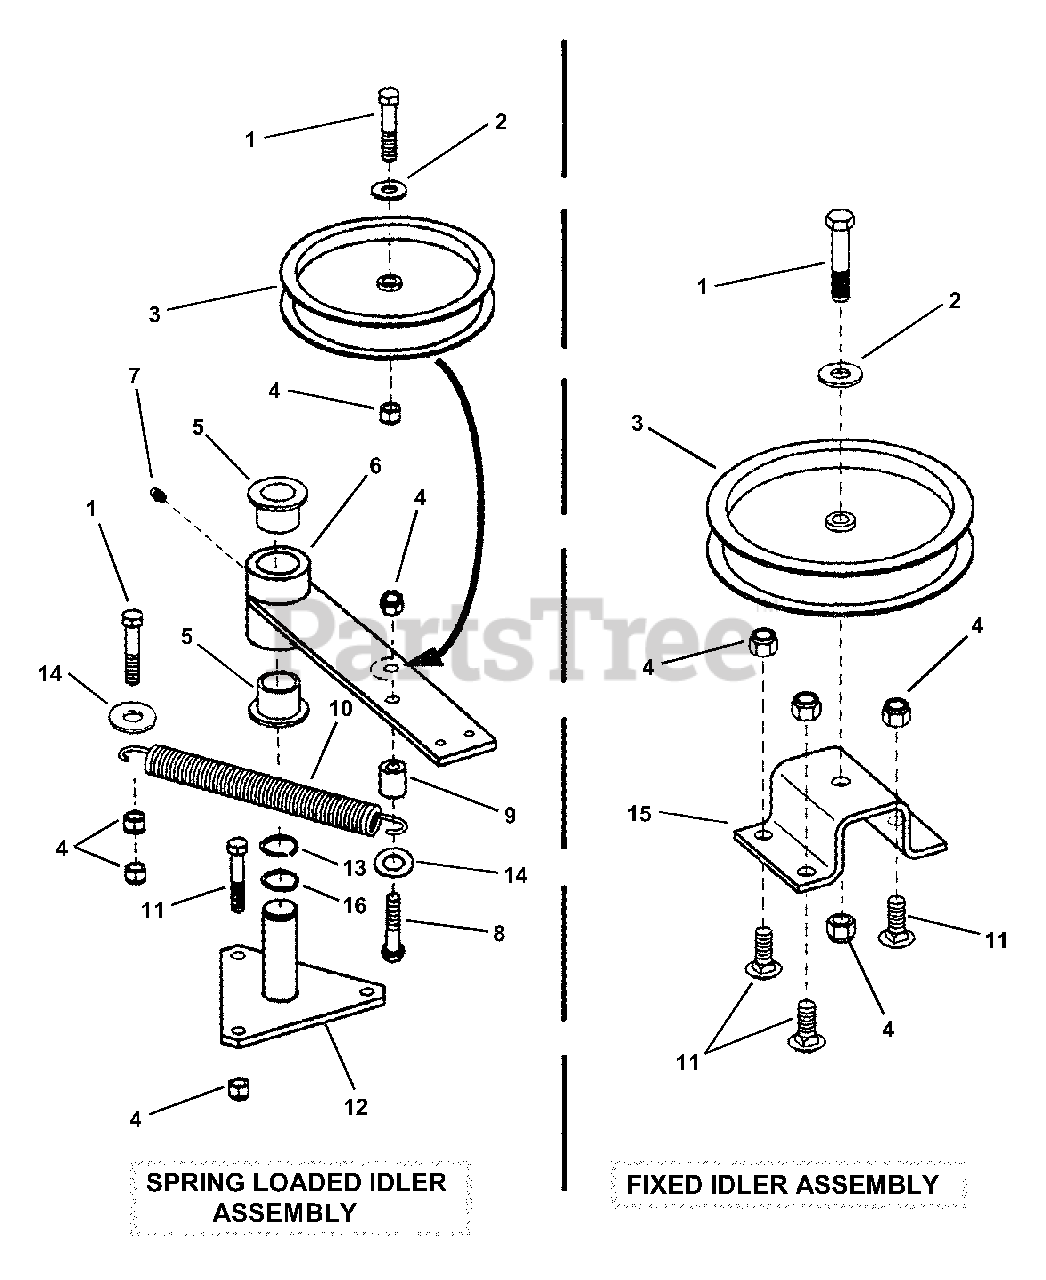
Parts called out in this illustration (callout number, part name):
1	BOLT, 3/8-16 X 2, GD5, CZ
2	WASHER, 3/8" USS
3	PULLEY, Idler 5-1/2" O.D.
4	NUT, 3/8-16 HEX NYLON LOCK
5	BUSHING
6	ARM, Idler (Weldment)
7	FITTING, Lube 1/4-28 Straight
8	SCREW, 3/8-16 x 1-3/4" Hex Head Cap, Grade 5
9	SPACER, .50 I.D. x .75 O.D. x .83
10	SPRING, Extension
11	BOLT, 3/8-16 x 1" Square Neck Carriage, Grade 5
12	PLATE, Tri-Mount (Weldment)
13	E-RING 1"
14	WASHER, .406 x 1.5 x .120 Yellow Zinc
15	STAND, Fixed Idler
16	WASHER, 1.031 x 1.25
